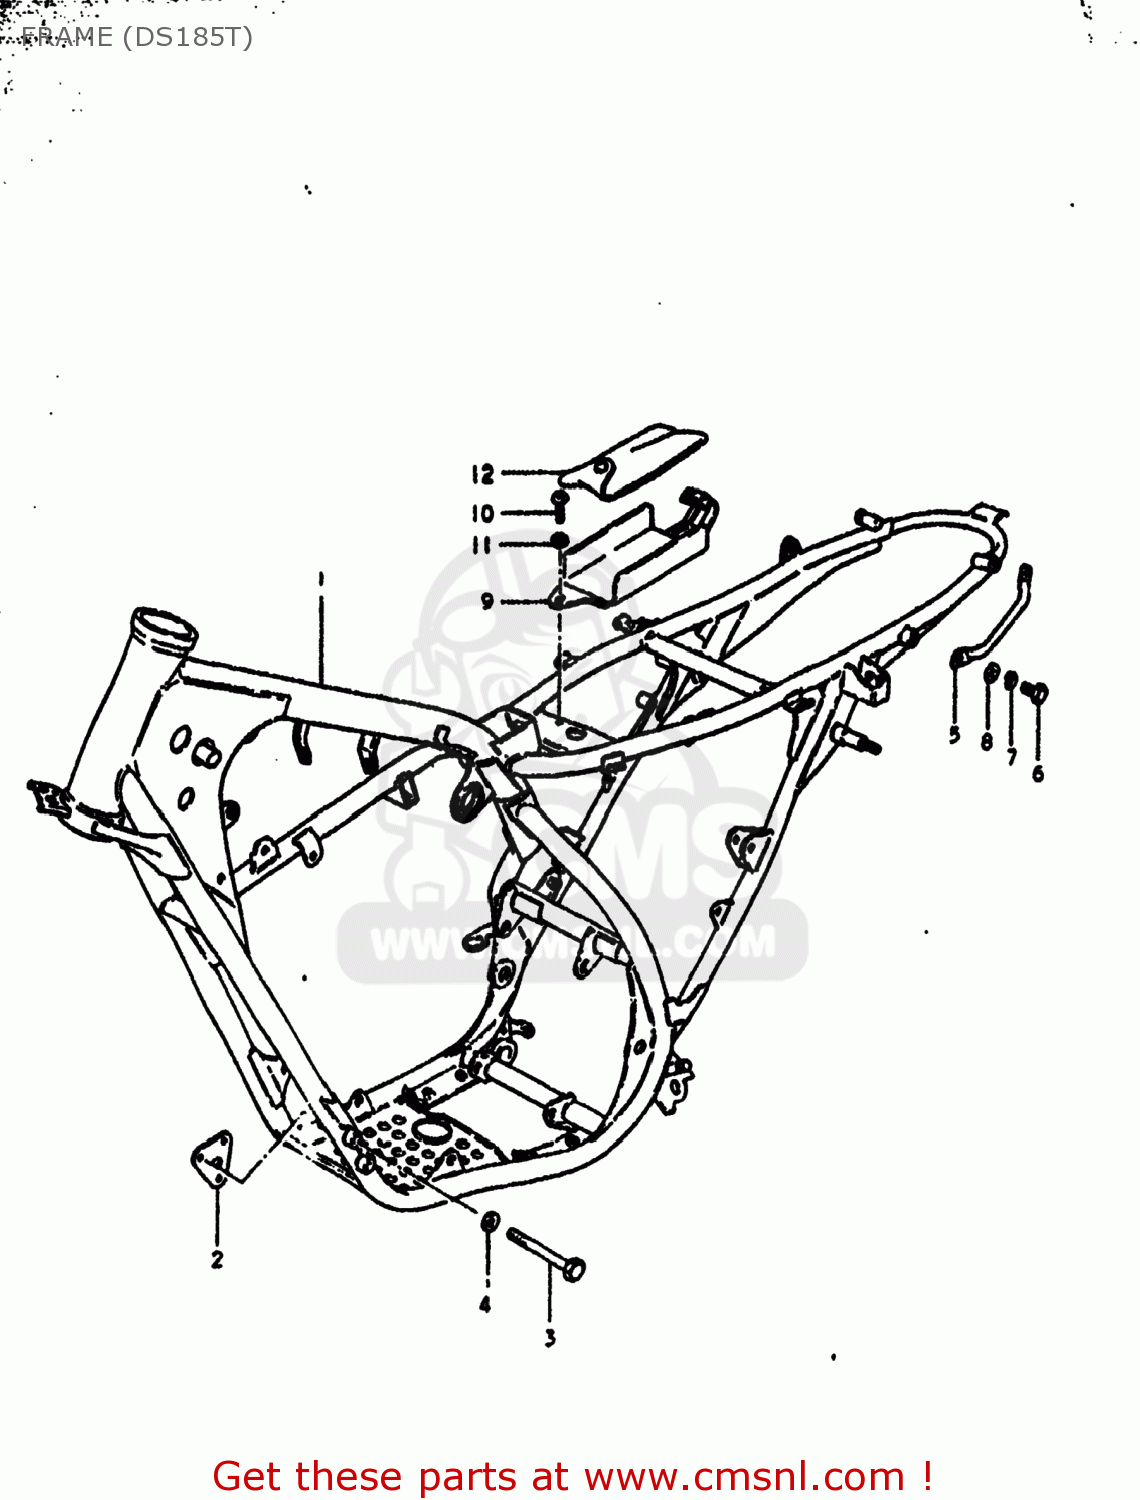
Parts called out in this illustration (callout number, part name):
1	FRAME
2	PLATE,ENG MTG,L
3	BOLT 8X55
4	WASHER
5	GRIP,FRAME HANDLE
6	BOLT, UPPER
7	LOCK WASHER
8	WASHER
9	HOLDER,TOOL
10	SCREW
11	WASHER
12	TOOL ASSY
